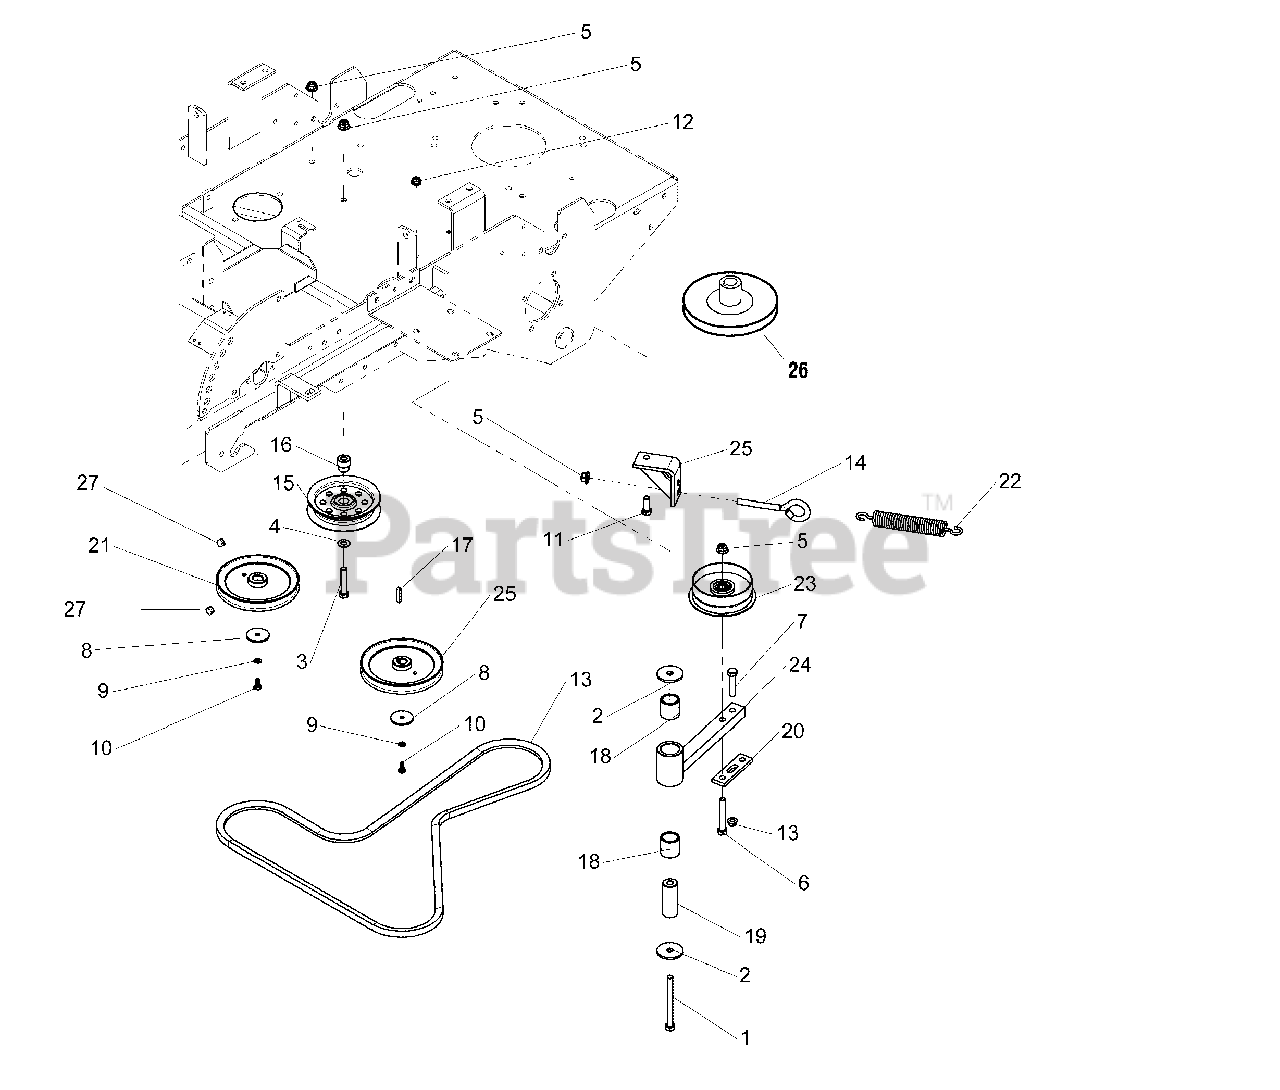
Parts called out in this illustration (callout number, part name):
1	BOLT, 3/8-16 X 4" GD5
2	WASHER, .41 X 1.75 X .14
3	BOLT, 3/8-16 X 2" GD5
4	WASHER 3/8" SAE
5	NUT, 3/8-16 HEX NYLOCK FLANGE
6	BOLT, 3/8-16 X 2-1/2" GD5
7	BOLT, 3/8-16 X 1-3/4" GD5
8	WASHER, .265 X 1.50 X .109, YZ
9	WASHER, 1/4" LOCK
10	BOLT, M6-1.0 X 14MM
11	BOLT, 3/8-16 X 1" GD5
12	NUT, 5/16-18 HEX NYLOCK FLANGE
13	BELT, DECK DRIVE
14	EYE BOLT, 3/8-16 X 5", 1" EYE
15	PULLEY, IDLER
16	SPACER, HYDRO IDLER PULLEY
17	KEY, 5MM SQ W/ RADIUS
18	BUSHING, BRASS, 1.25 X 1 X 1.25
19	SPACER, .39 X 1.00 X 2.55
20	PLATE, ANCHOR, SPRING
21	PULLEY, PUMP DRIVE
22	SPRING, EXTENSION, SWIVEL END
23	PULLEY, IDLER, SINGLE FLANGE
24	WELD, ARM, PUMP DRIVE IDLER - BLK
25	WELD, ANCHOR EYEBOLT
26	PULLEY, Crankshaft
27	SET SCREW, 5/16-18 X 1/2
